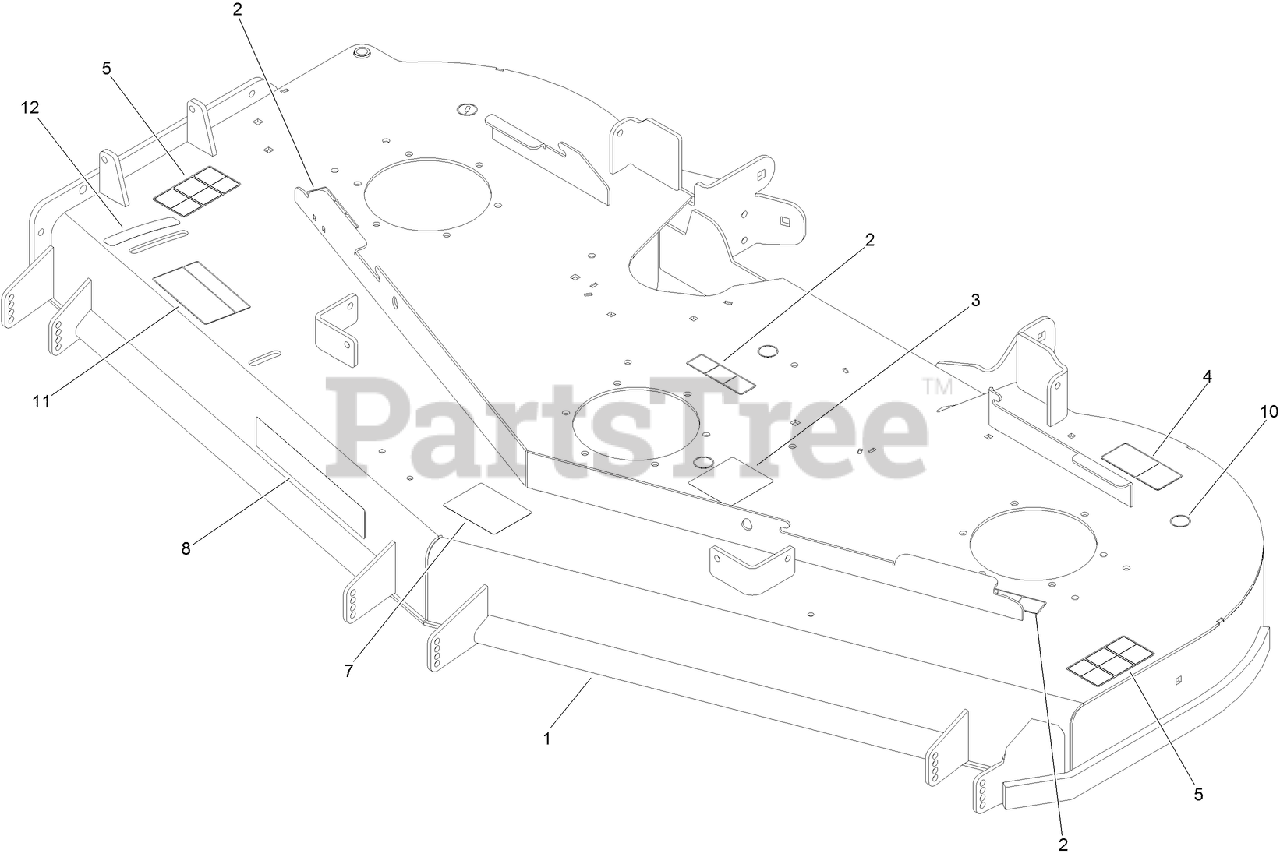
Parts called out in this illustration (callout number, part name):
1	DECK DECAL ASM
2	DECAL-COVER, MISSING
3	DECAL-ROUTING, DECK BELT
4	DECAL-TORQUE, BLADE BOLT
5	DECAL-DANGER
7	DECAL-SCALP, ANTI
10	DECAL-GREASE
11	DECAL-ADJUSTMENT, BAFFLE
12	DECAL-SETTING, BAFFLE
